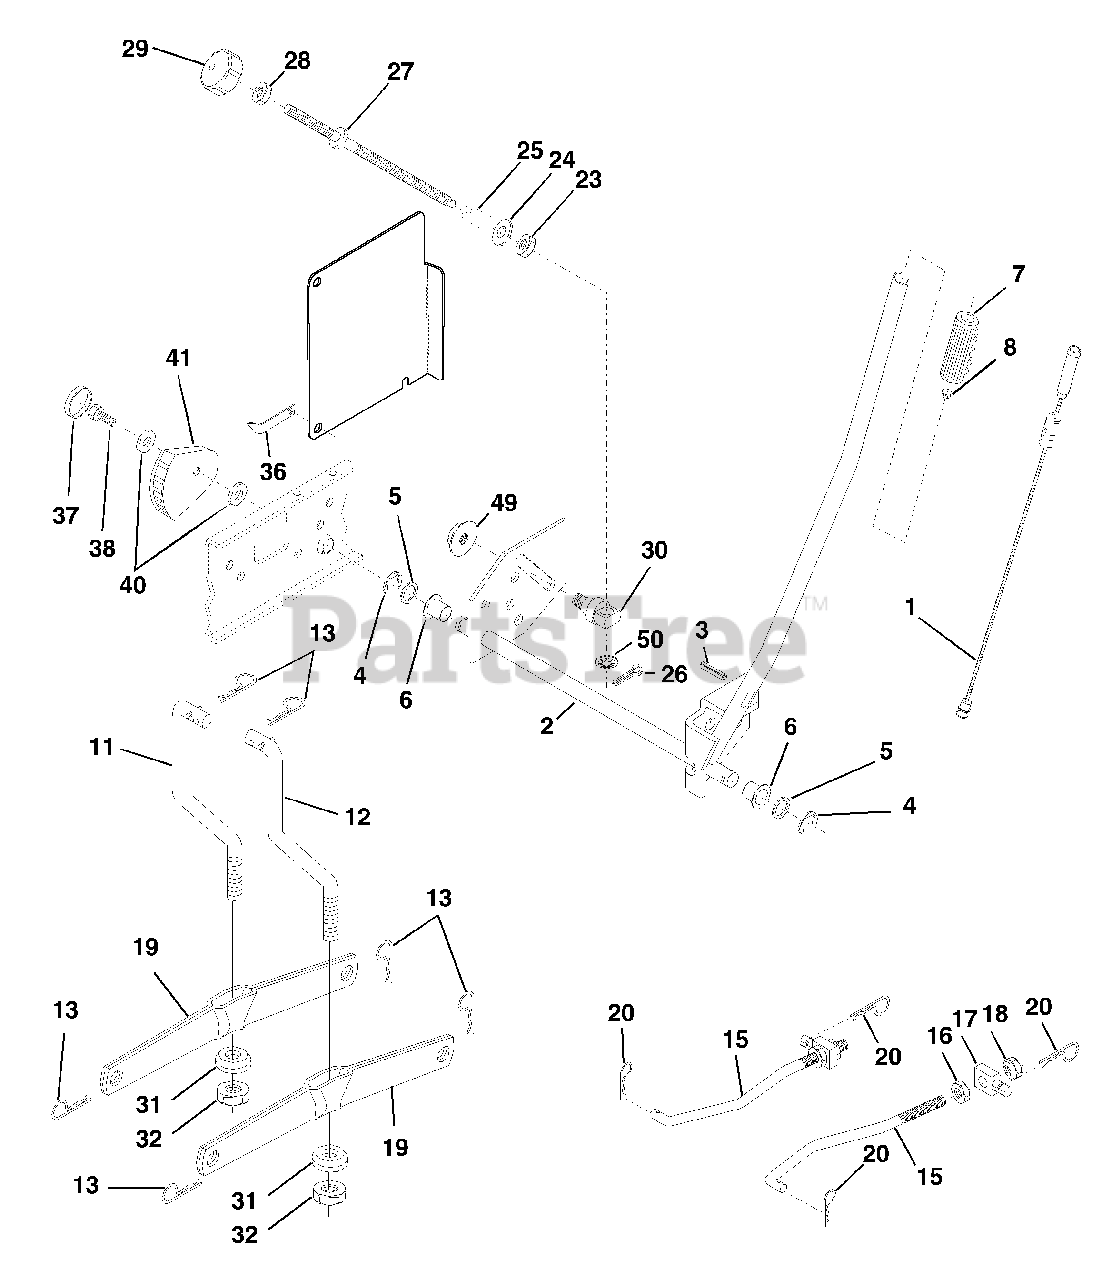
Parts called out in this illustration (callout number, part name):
1	Wire Asm Inner/Spring W/Plunger LT
2	Shaft Asm Lift RH w/Inf
3	Pin Groove 1 500 Zinc
4	E Ring #5133-62
5	Washer 21/32 X 1 X 21 Ga
6	Bearing Nylon Blk 629 Id
7	Grip Handle Fluted Blk
8	Button Plunger Black
11	Link Lift LH Fixed Length
12	Link Lift RH Fixed Length
13	Retainer Spring
15	Link Front
16	Nut Jam Hex 1/2-13 Unc
17	Trunnion Blk Zinc
18	Nut Crownlock 1/2-13unc
19	Arm Suspension Rear
20	Retainer Spring
23	Nut Special
24	Washer 13/32 X 5/8 X 16 Ga
25	Spring 2-1/8"
26	Pin Cotter 3/32 X 1/2
27	Rod Adj Lift Zinc 7.49 Wrk Lg
28	Nut Hex Jam 3/8-16 Unc
29	Knob Inf 3/8-16 Unc Blk W/sym
30	Trunnion Infin Height
31	Bearing Pvt Lift Spherical
32	Nut Crownlock 3/8 - 24
36	Indicator Height STLT
37	Plug Hole Blk 1.485/1.515 Dia.
38	Screw Thdrol 5/16-18 x 3/4
40	Washer 11/32 x 1-1/2 10 Ga.
41	Scale Ind. Height Blk.
49	Nut Hex Flange Lock
50	Nut, Push Phos & Oil
